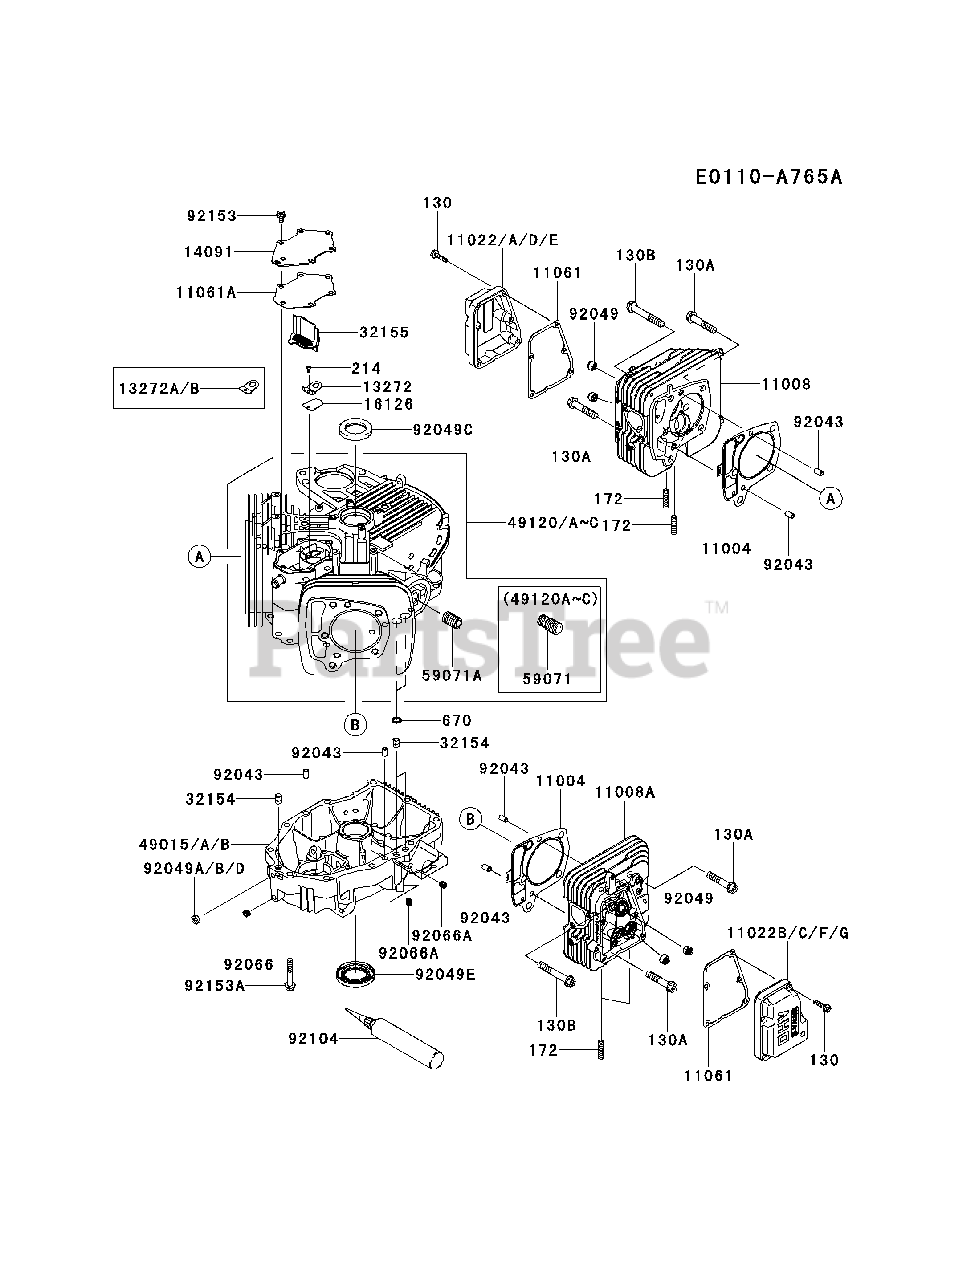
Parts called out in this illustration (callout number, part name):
130	BOLT-FLANGED,6X25
130A	BOLT-FLANGED,10X50
130B	BOLT-FLANGED,10X65
172	BOLT-STUD,8X18
214	SCREW-PAN+-,4X8
670	O RING,11MM
92153A	BOLT,8X50
